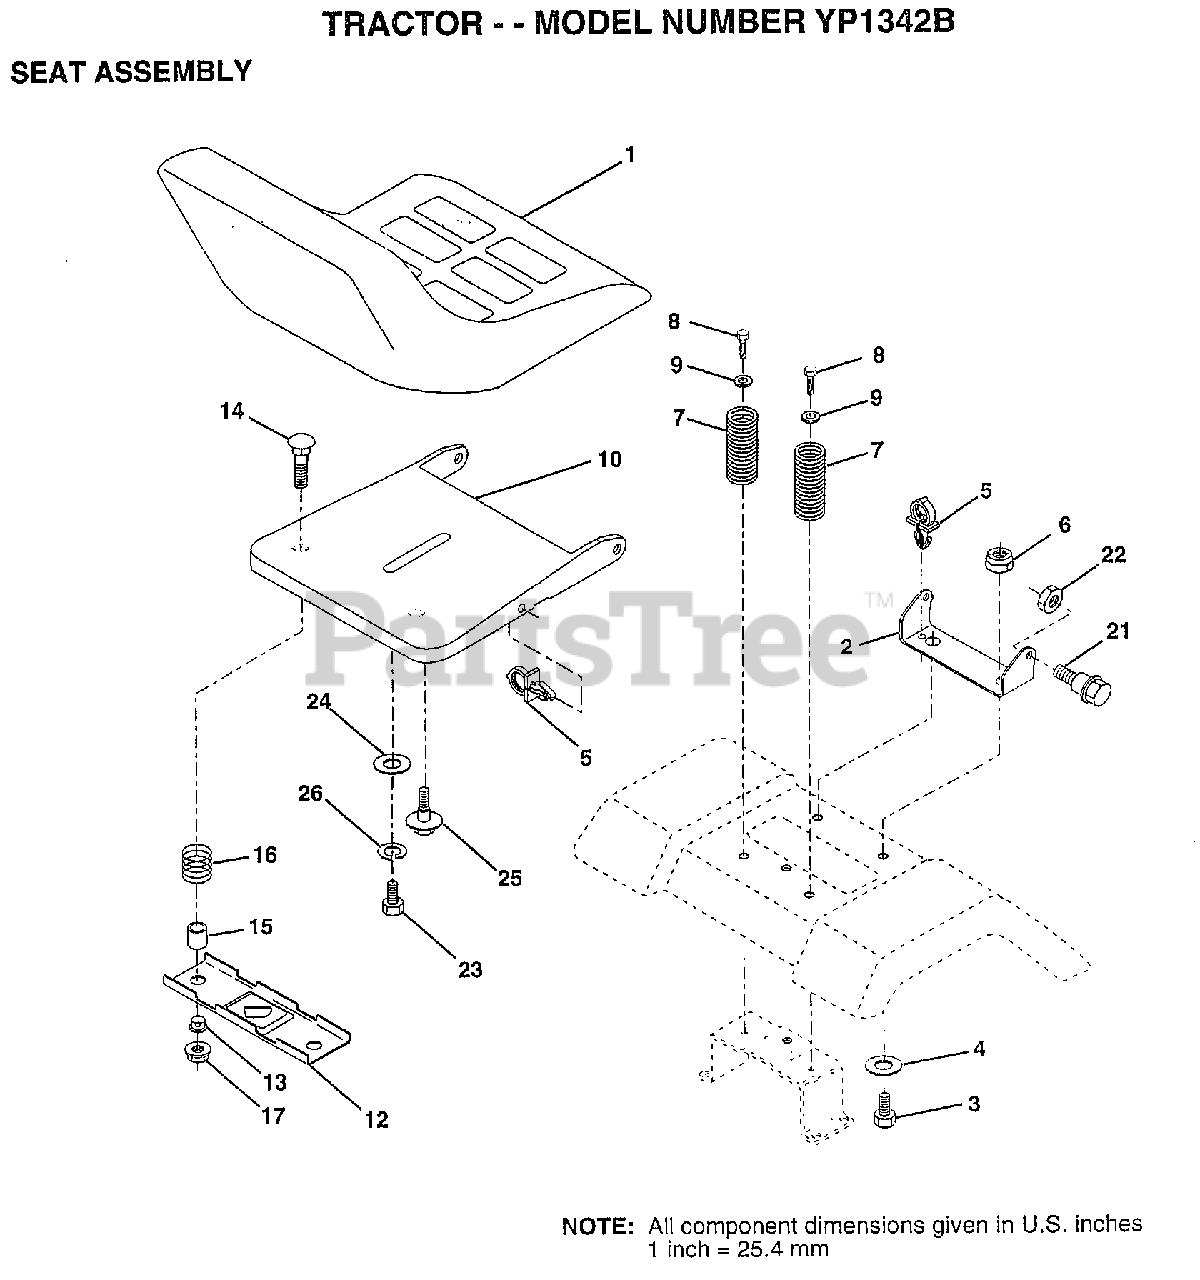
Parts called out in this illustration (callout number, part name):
1	SEAT
2	BRACKET PVT SEAT
3	BOLT
4	WASHER PM
5	CLIP.PUSH-IN.HING
6	NUT
7	SPRING COMPRESSIO
8	SCREW GTV
9	WASHER
10	PAN-SEAT
12	BRKT SWITCH
13	BUSHING
14	BOLT-RD HD SQ NK
15	SPLIT SPACER
16	SPRING
21	"BOLT,SHOULDER"
22	NUT
23	BOLT
24	WASHER
25	"BOLT,SHOULDER"
26	LOCKWASHER
